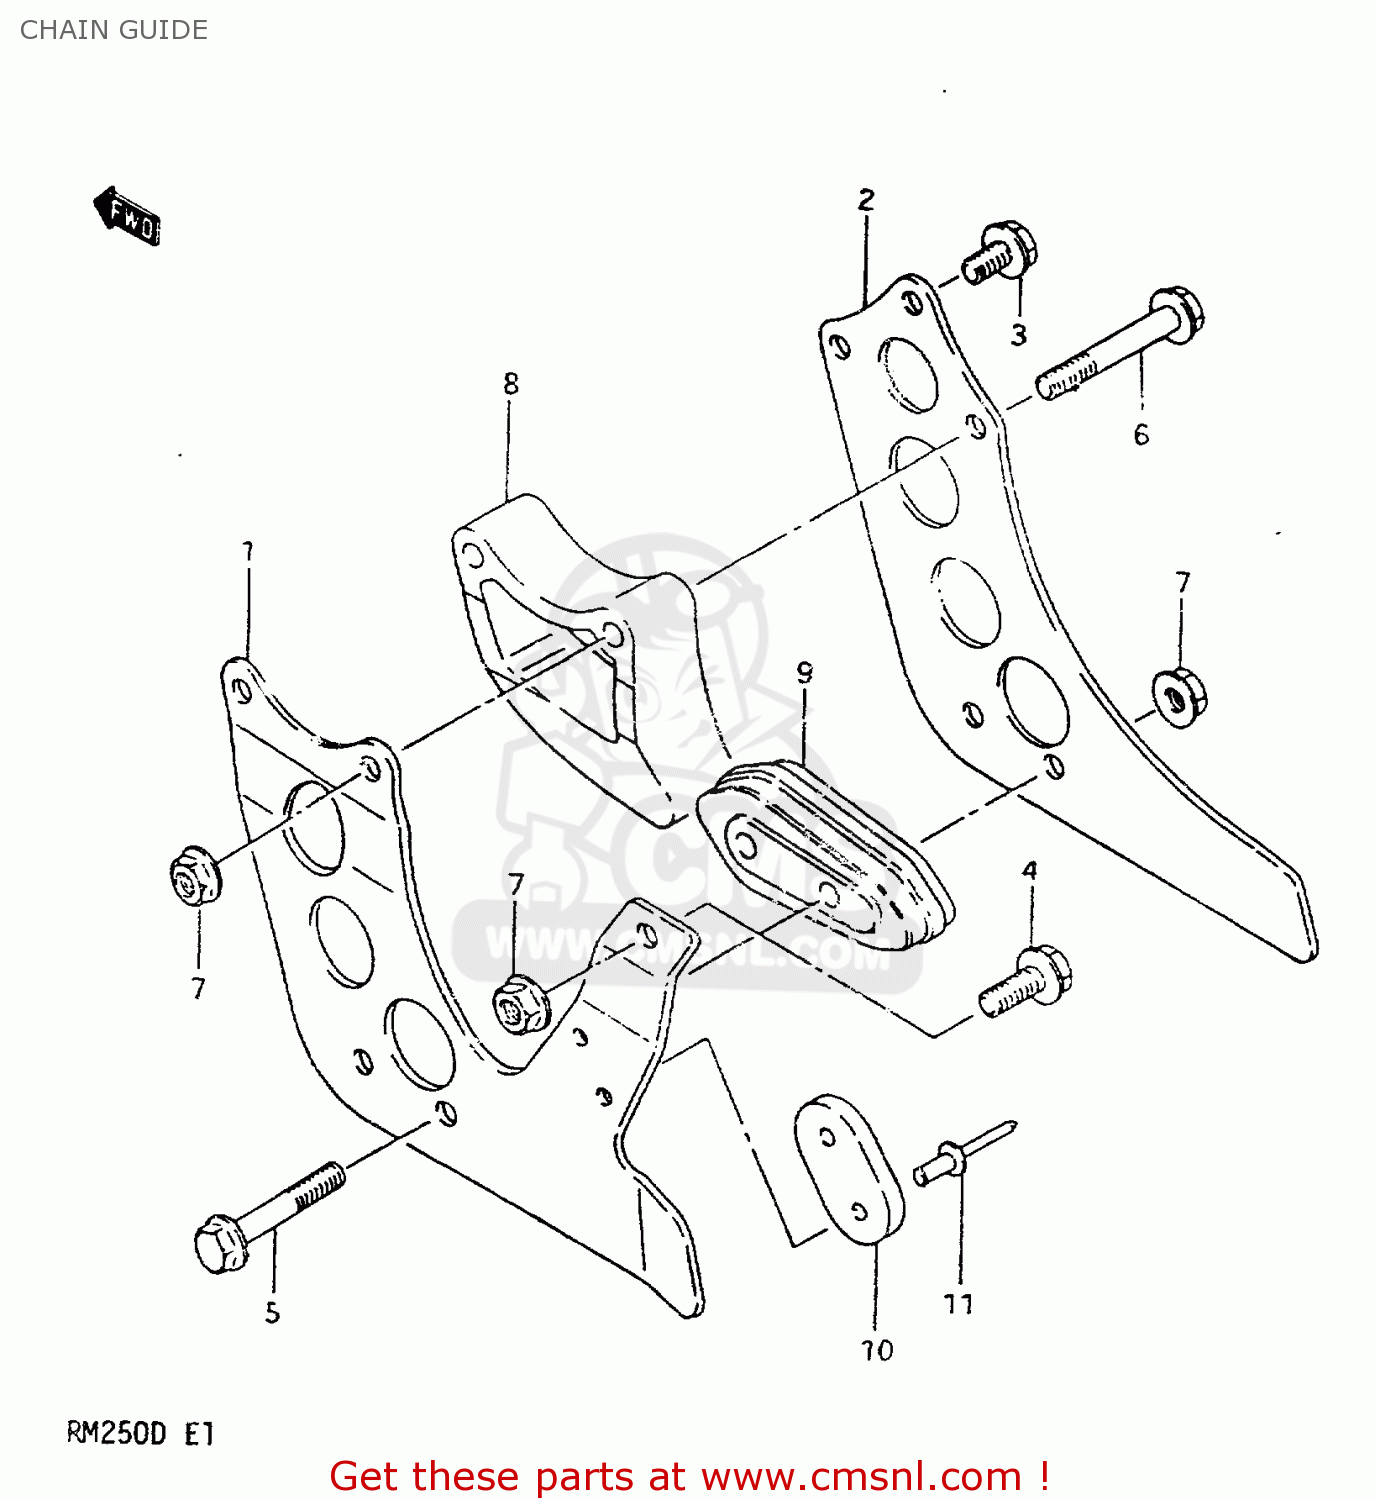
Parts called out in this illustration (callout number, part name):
1	PLATE,OUTER
2	PLATE,INNER
3	BOLT 6X12
4	BOLT 6X16
5	BOLT
6	BOLT,UNDER
7	NUT
8	DEFENSE,CHAIN GUIDE UPR
9	DEFENSE,CHAIN GUIDE
10	PAD,CHAIN GUIDE
11	RIVET
